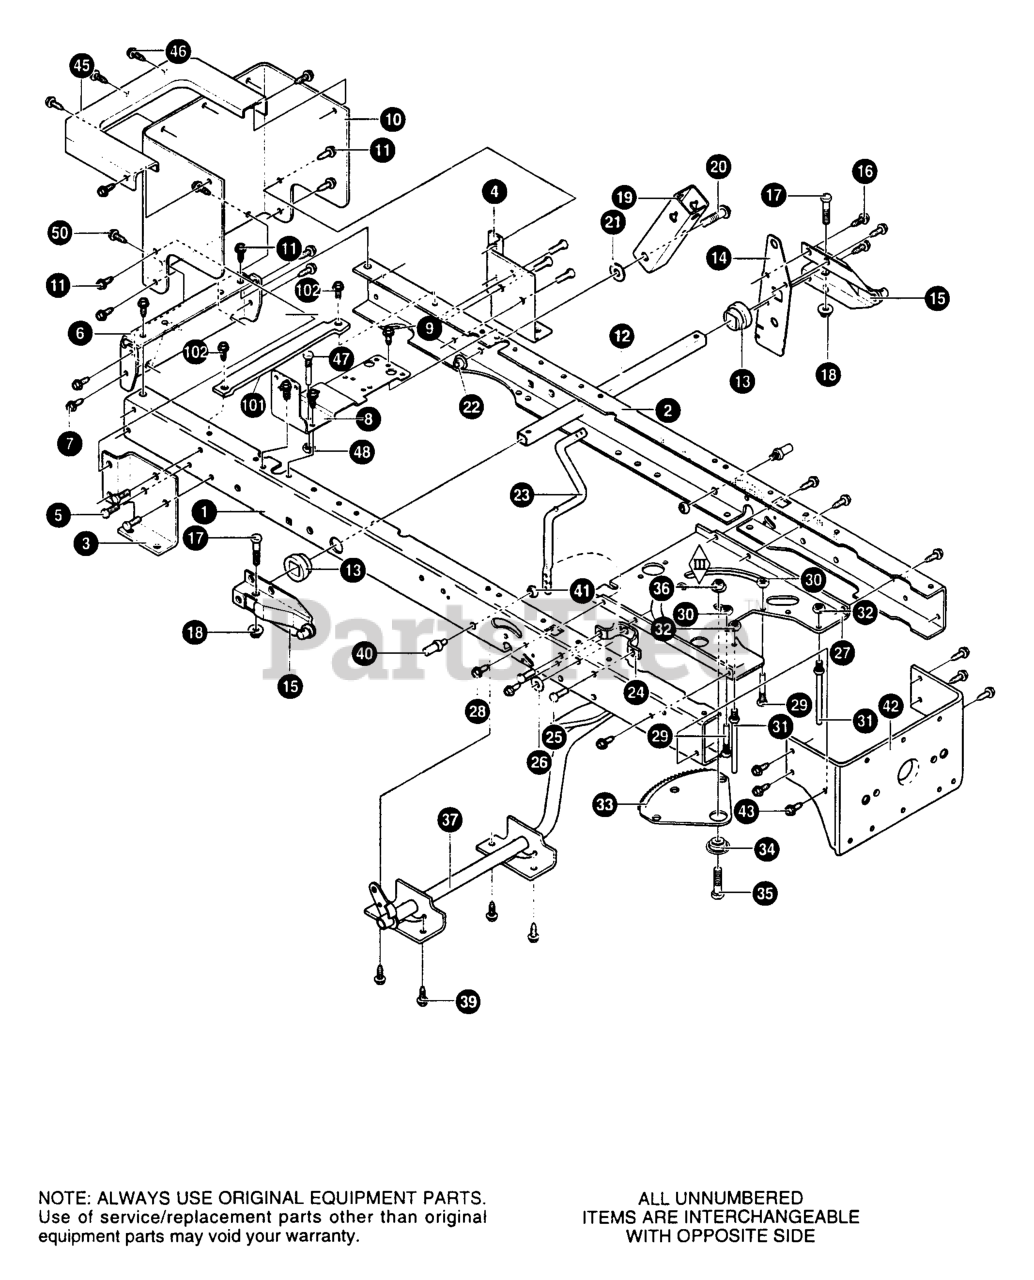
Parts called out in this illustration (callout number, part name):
1	FRAME,RAIL RH
2	FRAME,RAIL LH
3	BRACKET, TRANSAXLE RH
4	BRACKET, TRANSAXLE LH
5	SCREW, 5/16-18 x .75 HHWATAP
6	HITCH PLATE
7	SCREW, 5/16-18 x .75 HHWATAP
8	BRACKET, SHIFT RH
9	SCREW 5/16-18X.75HHWATAP
10	PLATE, REAR
11	SCREW, 5/16-18 x 0.75 HHWATAP
12	TUBE, LIFTER
13	BUSHING, LIFT TUBE
14	PLATE-LIFT ARM
15	ASSY, LIFT ARM LEVER
16	SCREW, 5/16-18 x 0.50 WHHTAP (26X49)
17	SCREW, 5/16-24 x 1.25
18	NUT, 5/16-24 NF-2 HEXFLLK
19	BRACKET, PIVOT
20	BOLT, .562X1.563 HHSH 3/8-16
21	FLATWASHER.406ID (17X191)
22	NUT, 3/8-16 HWDFLLK MACK 15X84
23	CRANK, PTO
24	BRACKET, BELL CRANK
25	SCREW, 5/16-18 x .75 HHWATAP
26	FLATWASHER .469X.92X.065
27	PLATE, STEERING
28	SCREW, 5/16-18 x .75 HHWATAP
29	SCREW GUIDE 5/16-18
30	NUT, 5/16-18 HEXWEFLLK WHIZ
31	SCREW - GUIDE
32	NUT, 5/16-18 HEXWDFLLK WHIZ
33	SECTOR GEAR
34	BEARING, SECTOR GEAR
35	SCREW, 5/16-18 x 1.00 HHC
36	NUT, 5/16-8 HKEPS 15X113
37	ASSEMBLY, BRAKE LEVER
39	SCREW, 5/16-18 x 0.75 HHWATAP
40	PIN, THREADED SHOULDER
41	NUT,3/8-16HWDFLWHIZ-LOCK
42	BRACKET, HANGER REAR
43	SCREW, 5/16-18 x 0.75 HHWATAP
45	TOP, REAR PLATE LG SEAT DECK
46	SCREW 10-24X.500TRSEGI
47	SCREW GUIDE 5/16-18
48	NUT, 5/16-18 HEXWDFLLK WHIZ
50	SCREW, 3/8-16 x 1.25 WAHHSPTAPP
101	BRACKET, BATTERY SUPPORT
102	SCREW, 5/16-18 x 0.75 HHWATAP
